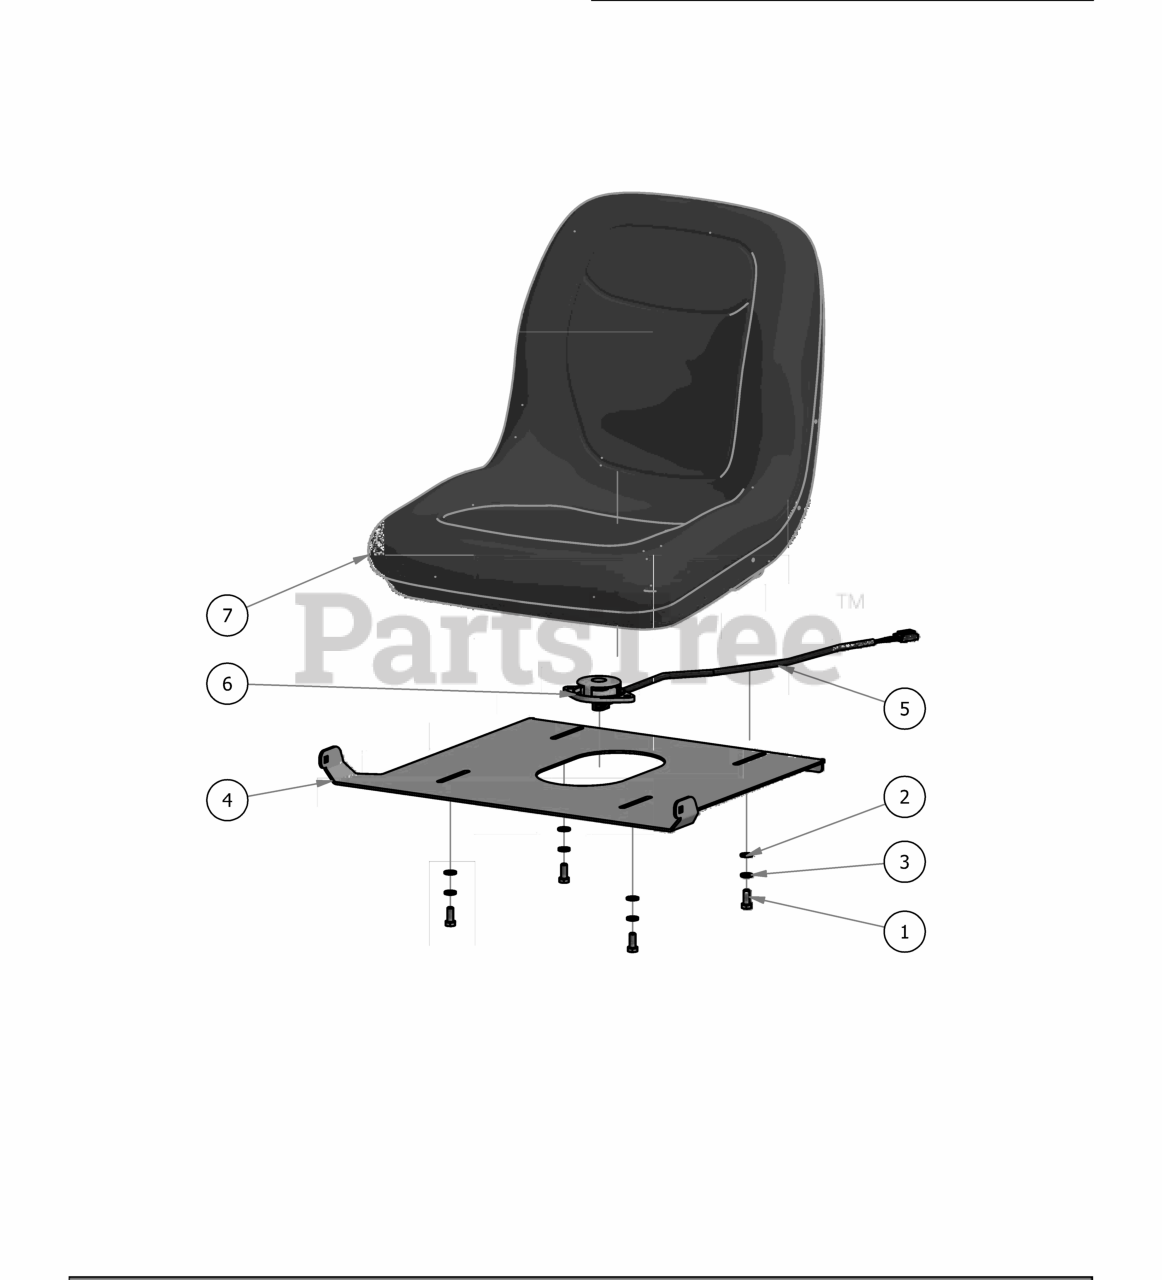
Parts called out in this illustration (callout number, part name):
1	5/16" x 3/4" Hex Bolt
2	1/4" Flat Washer
3	5/16" Lock Washer
4	2017 MZ Seat Plate
5	Seat Switch Adapter
6	SeatSafteySwitch
